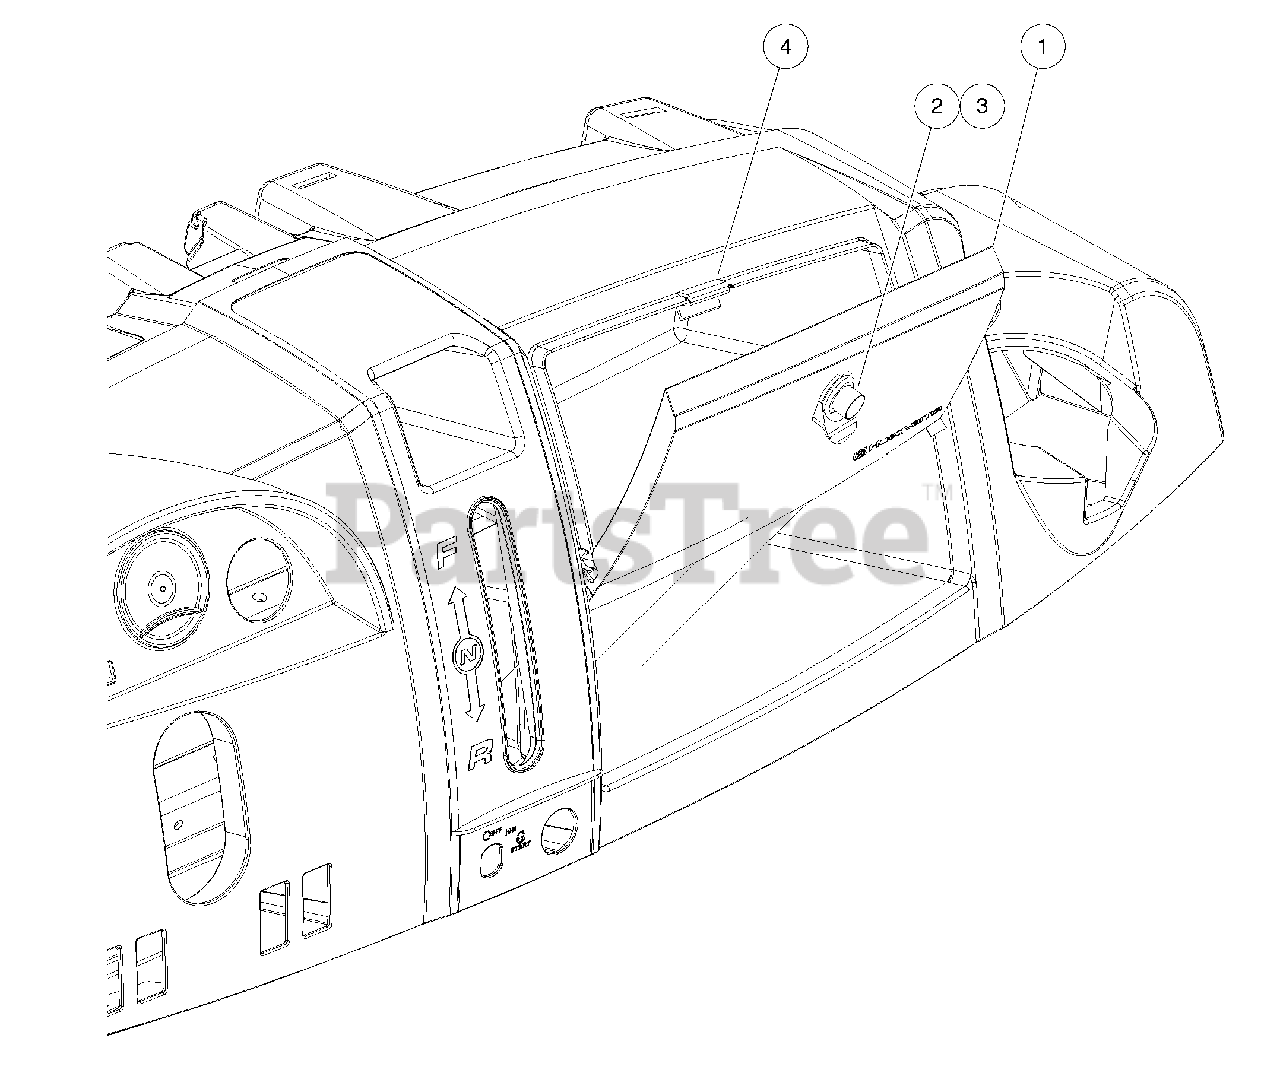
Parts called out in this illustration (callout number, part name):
1	Cover, Storage, Dash, Awd, Cci
2	Latch, Push Close
3	Latch, Push Close W/ Key
4	Keeper, Latch, Push Close
